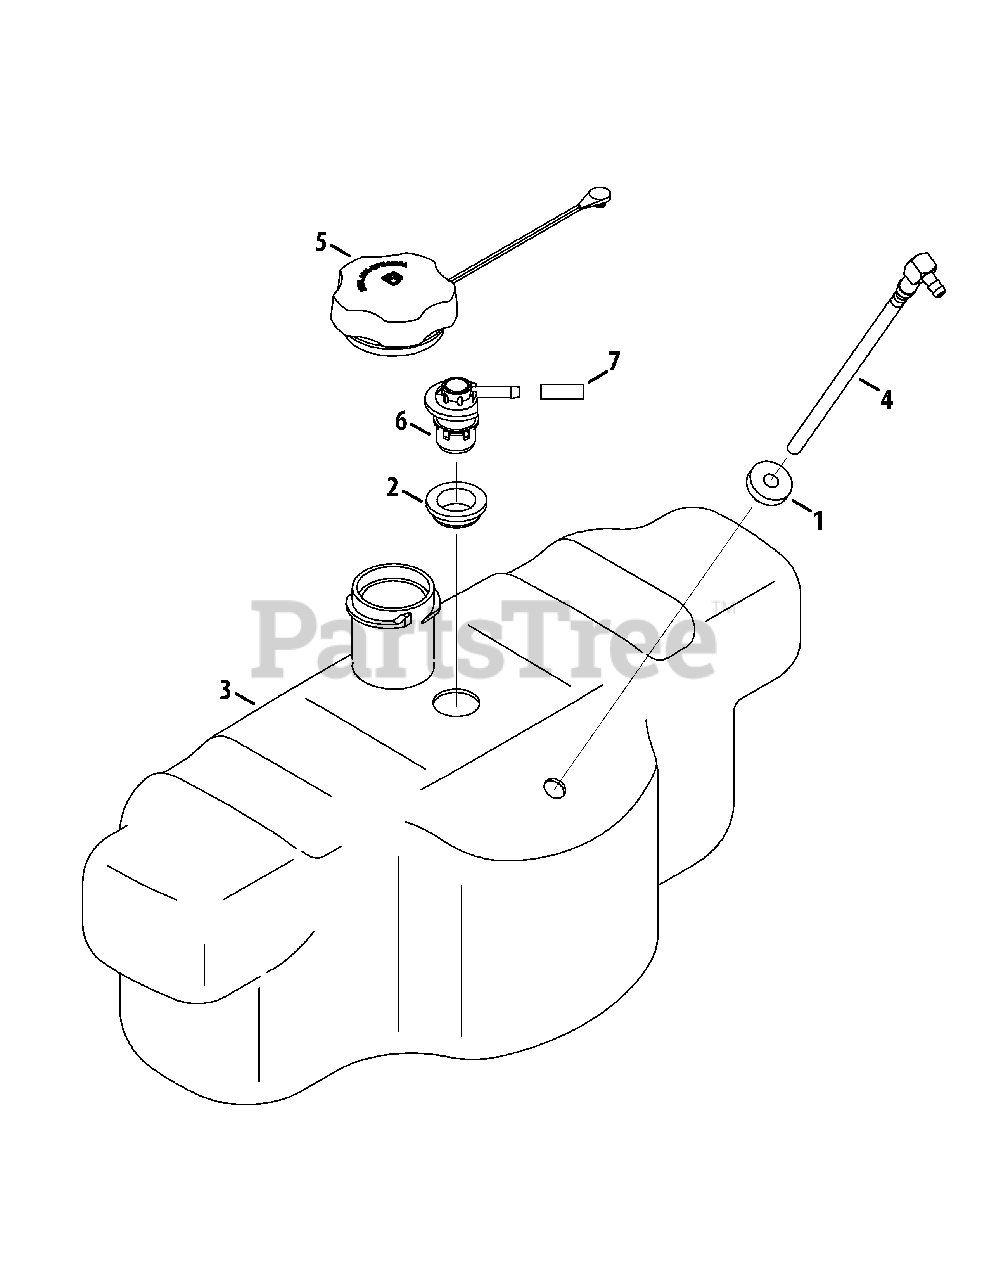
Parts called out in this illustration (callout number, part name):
1	Fuel Tank Bushing
2	Rubber Grommet
3	Fuel Tank
4	Fuel Pick-Up Fitting
5	Fuel Cap
6	Fuel Rollover Valve
7	Vent Hose
